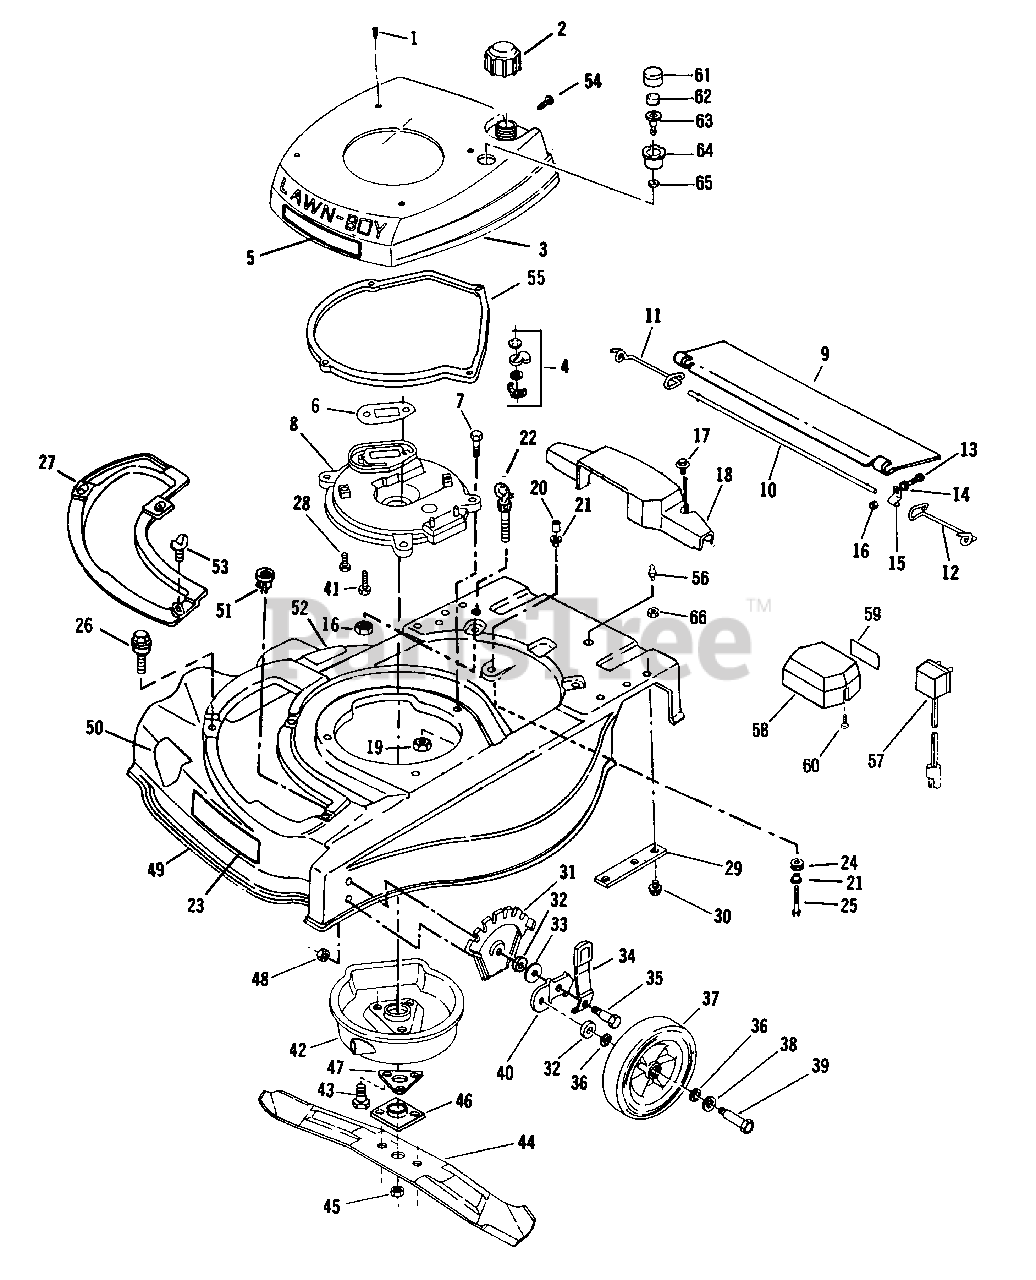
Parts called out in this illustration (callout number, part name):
1	Screw
2	Fuel Cap Assembly
3	Shroud Assembly
4	Fuel Shut-Off Assembly
5	Decal-Special
6	Gasket
7	Screw-Muffler Plate to Housing
8	Plate-Muffler
9	Shield-Trailing
10	Rod-Trailing Shield
11	Spring-R.H.
12	Spring-L.H.
13	Screw-Trailing Shield
14	Washer-Trailing Shield
15	Clamp
16	Nut-Trail Shield and Eyebolt
17	Screw-Axle Cover Mounting
18	Cover-Drive Axle
19	Nut-Muffler Plate to Housing
20	Spacer
21	Spacer
22	Eyebolt
23	Decal-Manual Start
24	Grommet
25	Screw-Transmission to Housing
26	Screw-Plate and Chute Mtg.
27	Cover Plate
28	Screw-Muffler Plate to Cylinder
29	Plate-Handle Brk't. Support
30	Screw-Handle Brk't. to Housing
31	Plate-Height Adjust
32	Washer
33	Washer-Wheel Mounting Brk't.
34	Knob and Spring Assem.
35	Bolt-Shoulder
36	Washer-Felt
37	Wheel-Front
38	Washer-Wheel Bolt Hd.
39	Bolt-Wheel-Front
40	Bracket-Wheel Hgt. Adjust.
41	Screw-Muffler Plate to Cylinder
42	Muffler Cover Assem.
43	Screw-Crankshaft Support
44	Blade-21"
45	Nut-Blade
46	Collar and Plate Assem.
47	Support-Crankshaft
48	Nut
49	Housing Assembly
50	Decal-Blade Contact Warning
51	Grommet
52	Decal-Discharge Area
53	Wing Screw
54	Screw-Shroud to C.D. Brk't.
55	Spacer-Shroud to Base
56	Ball Stud
57	Battery Charger Assem.
58	Battery Assem.
59	Decal-Caution
60	Screw
61	Primer Bulb
62	Filter
63	Base Primer Bulb
64	Cup Primer
65	Locknut
66	Nut
